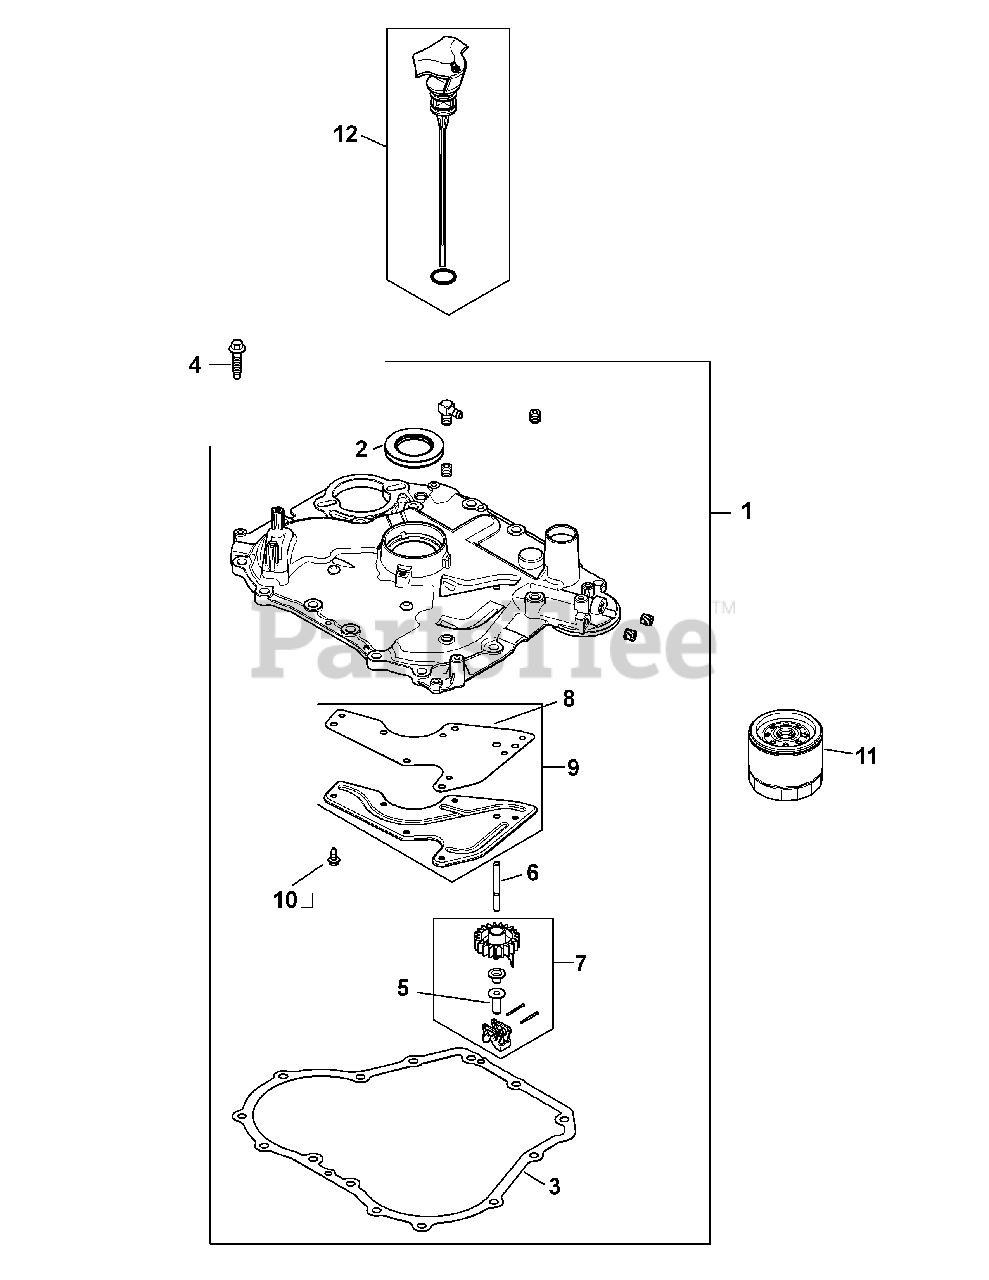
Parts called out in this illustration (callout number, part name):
1	Closure Plate Assembly
3	Closure Plate Gasket
4	Hex Flange Screw, 1/2
5	Governor Regulating Pin
6	Governor Cross Shaft
7	Governor Gear Assembly
8	Oil Passage Gasket
9	Oil Passage Cover Kit (Includes 7)
10	Flg. Thd. Frm. Screw, M5 X 0.8 X 13
12	Dipstick Assembly
12	Dipstick O-ring
